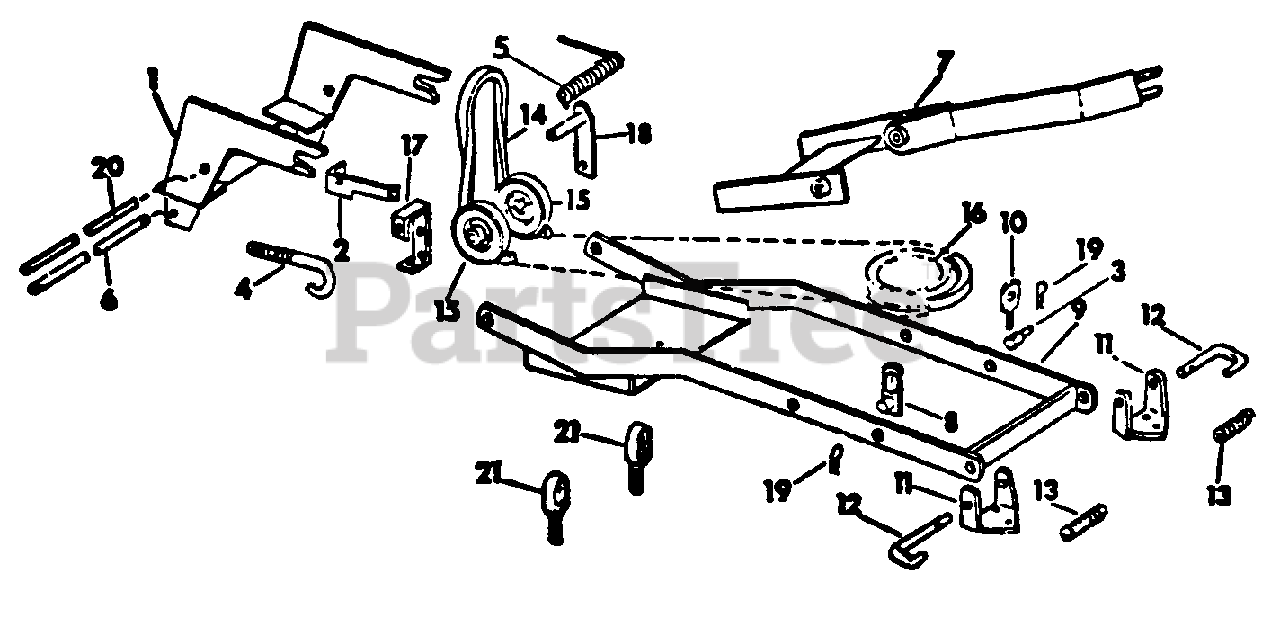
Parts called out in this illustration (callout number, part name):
1	Hanger Assy, Front
2	Ratchet, Idler
3	Block, Adjusting
4	Bolt, Idler Adjusting -Replaces 59 685 C1
5	Spring, Mule Drive Idler
6	Shaft, Front Hanger
7	Frame Assy, Center
8	Link Assy, Lift
9	Frame Assy, Outer Lift
10	Link, Adjustable Lift
11	Bracket, Mower Support
12	Pin, Mower Support
13	Spring, Mower Support Pin
14	Belt, Mule Drive
15	Pulley, Drive Belt Idler
16	Pulley, Center
17	Arm, Idler LH
18	Arm Assy, RH Idler
19	Pin, Quick Attachable Cotter
20	Shaft, Idler Pivot
21	Hanger, Mower Support Frt
